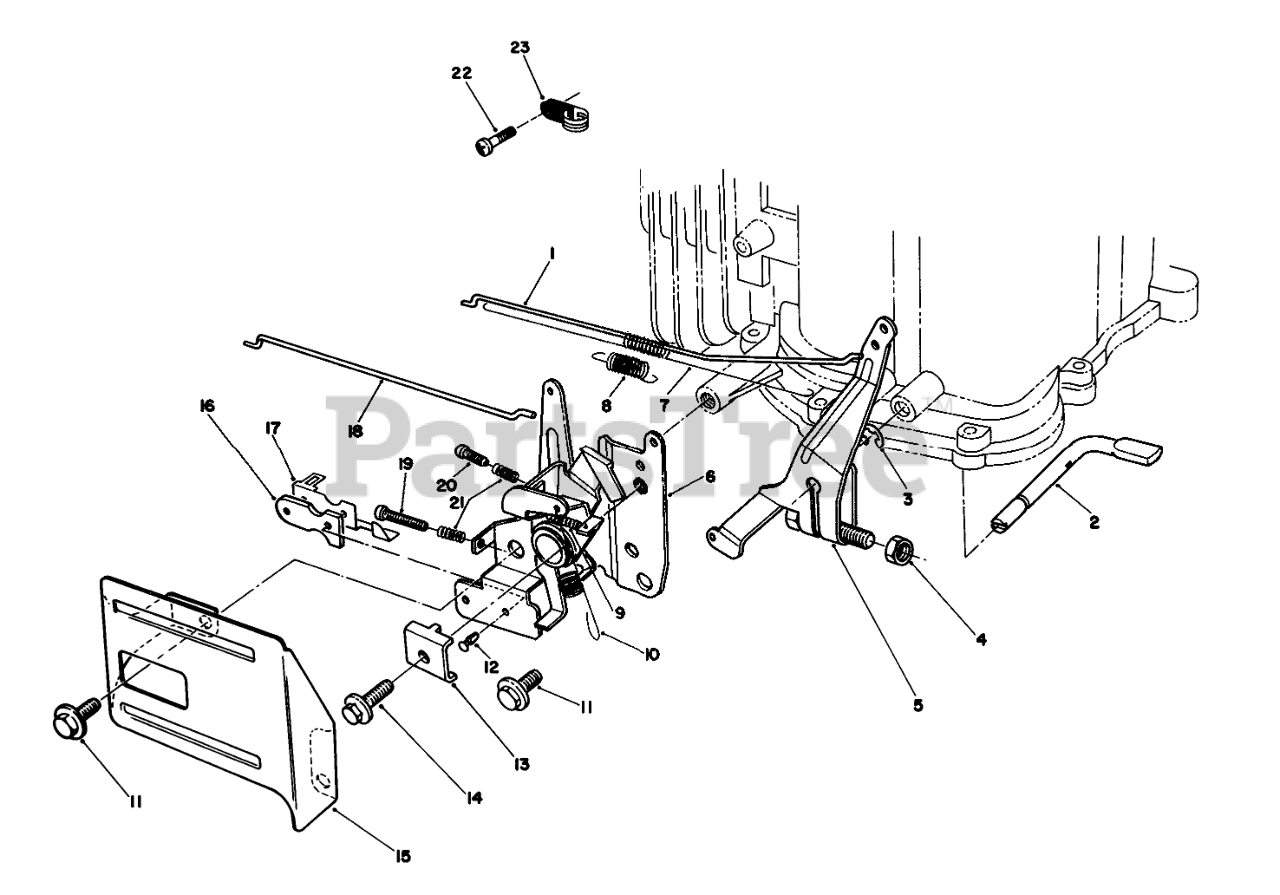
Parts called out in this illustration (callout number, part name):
1	Rod-Carburetor
2	SHAFT
3	E-RING
4	Nut
5	ARM ASM
6	THROTTLE
7	SPRING
8	SPRING
9	SPRING
10	SPRING
12	RIVET
13	CLAMP-CABLE
15	THROTTLE GUARD
16	INSULATOR-KILL SWITCH
17	TERMINAL-KILL SWITCH
18	Rod-Choke
19	SCREW
20	SCREW
21	SPRING
22	SCREW
23	Clamp
